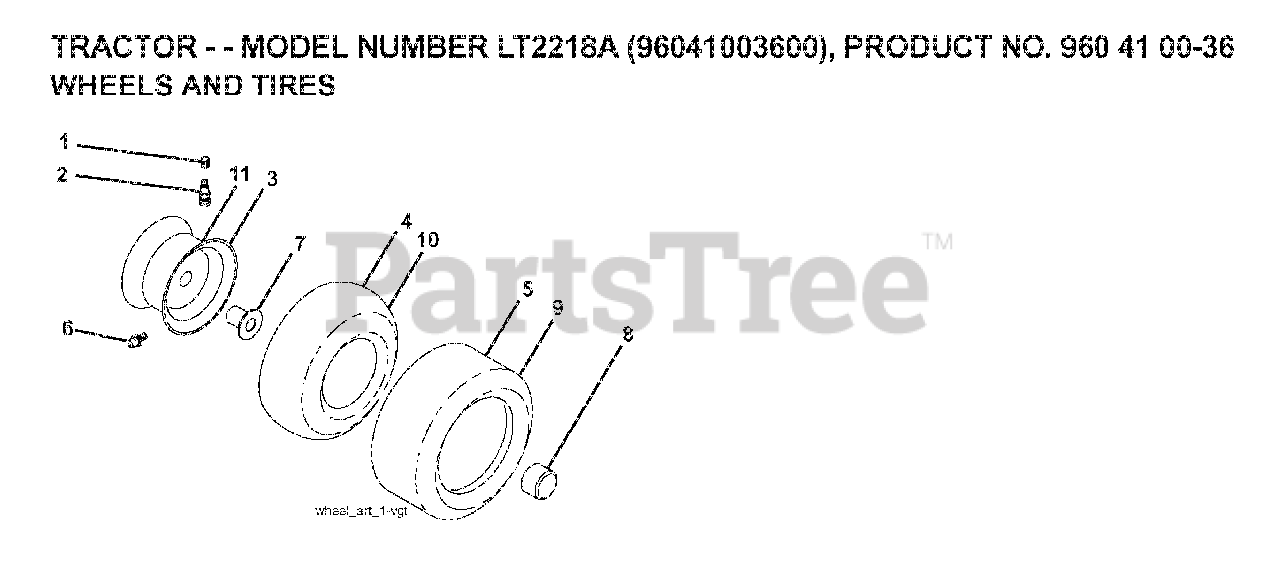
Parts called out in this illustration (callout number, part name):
1	VALVE CAP
2	VALVE STEM LT
3	RIM ASM 6" FRONT SILVER
4	TUBE.5.3/4.5/6
5	TIRE HEAVY DUTY
6	FITTING LT
7	BEARING T
8	CAP, AXLE BLK
9	TIRE.TS.20X10-8
10	TUBE
11	RIM ASM 8" REAR SILVER
